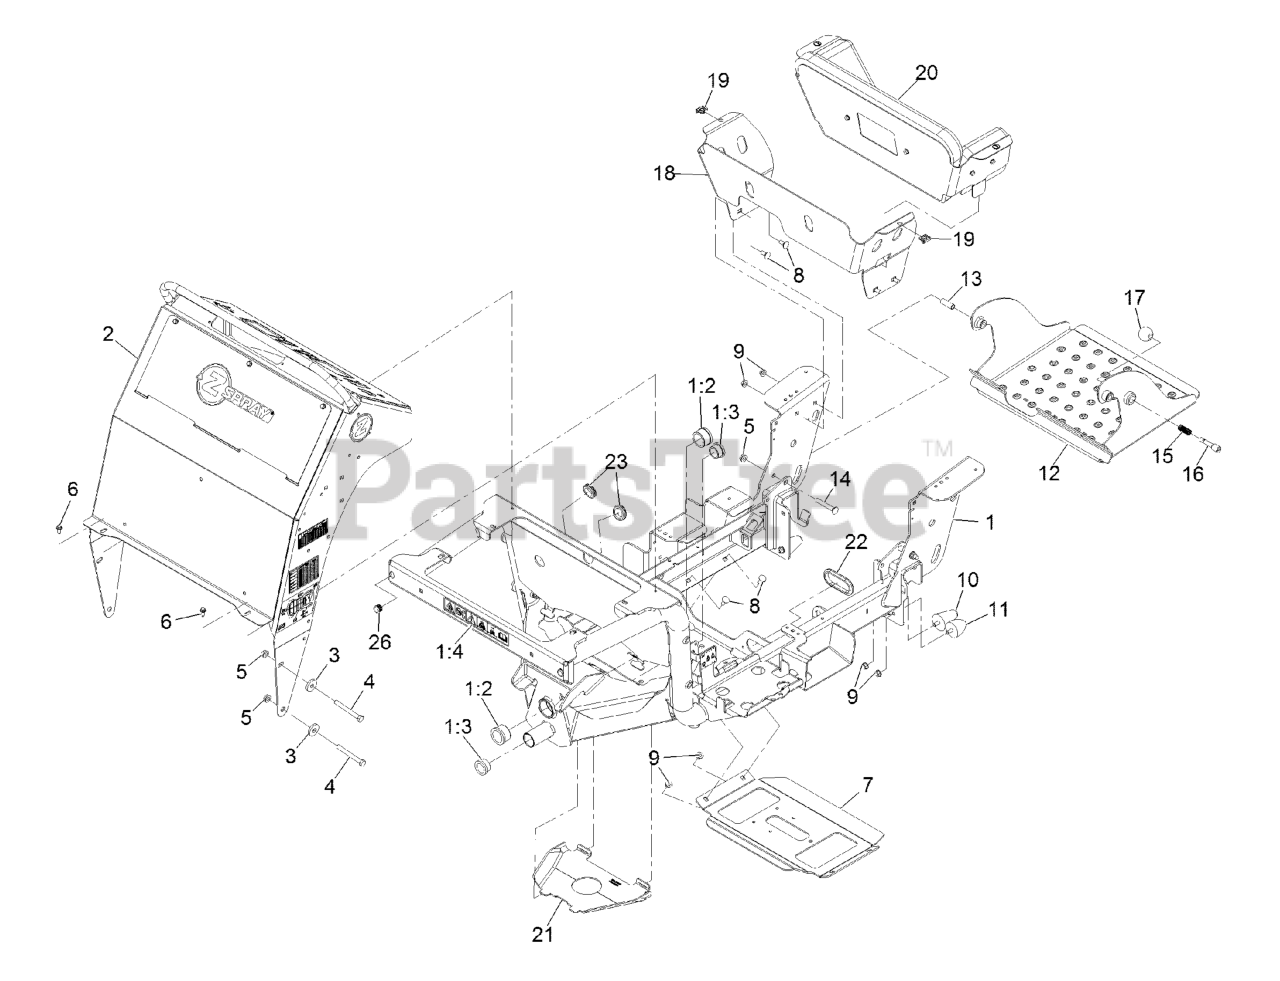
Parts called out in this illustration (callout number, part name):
1	Frame ASM
1:2	BEARING-FLANGED
1:3	BEARING-FLANGED
1:4	DECAL-DOWN, TIE
2	Control Tower ASM
4	SCREW-HH
6	SCREW-HWH
7	GUARD-LOWER
8	SCREW-CARR
10	BUMPER-RUBBER
11	BUMPER-RUBBER
12	OPERATOR PLATFORM ASM
13	BUSHING-PIVOT, PLATFORM
14	SCREW-CARR
16	PIN-LATCH
17	KNOB-BALL
18	MOUNT-PAD, KNEE
19	RECEPTACLE-CLIP, MINI
20	ASM-Pad
21	SHIELD-DUST
22	GROMMET
23	GROMMET
26	PLUG-TUBE
